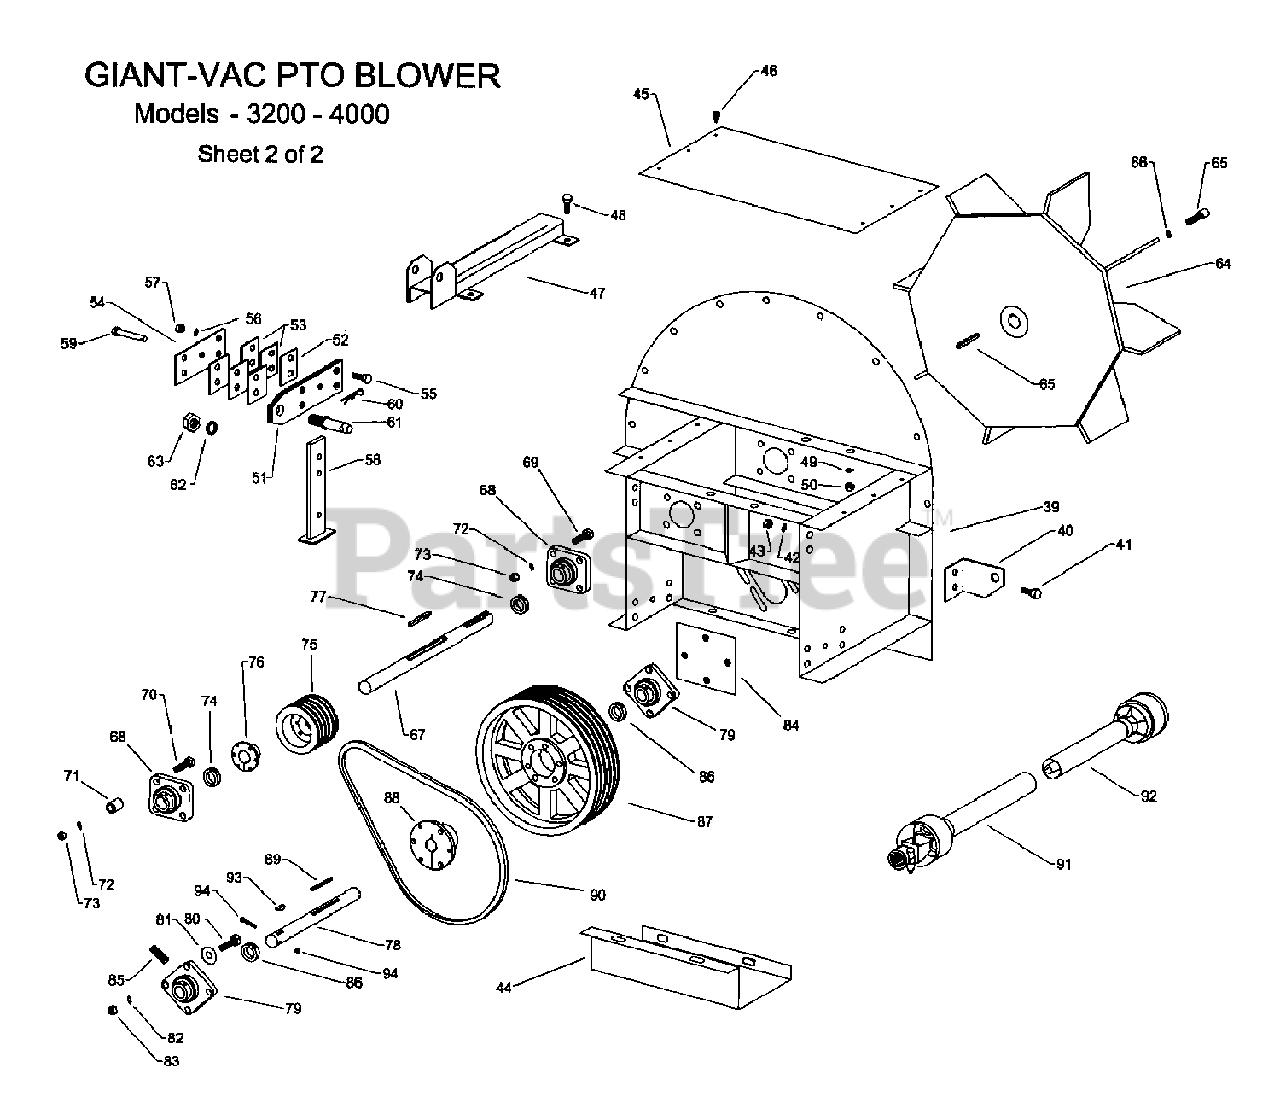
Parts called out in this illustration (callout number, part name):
39	Blower back & shaft frame
40	Control rod guide bracket
41	1/2 x 1-1/4 hex bolt
42	1/2 lockwasher
43	1/2 hex nut
44	Shaft frame bottom cover
45	Shaft frame top cover plate
46	#12 x 3/4 self tapping screw
47	Top hitch point bracket
48	1/2 x 1-1/4 hex bolt
49	1/2 lockwasher
50	1/2 hex nut
51	Hitch lower point plate
52	Jack stand spacer - 1/8
53	Jack stand spacer - 1/4
54	Jack stand side support plate
55	1/2 x 3-1/2 hex bolt
56	1/2 lockwasher
57	1/2 hex nut
58	Jack stand
59	Jack stand pin
60	Jack stand hair clip
61	Hitch pin
62	7/8 hitch pin lockwasher
63	7/8 hitch pin nut
64	Impeller, 33"
64	Impeller, 34"
65	Impeller bolt & key (5/8 x 3)
66	5/8 lockwasher
67	Impeller shaft
68	Impeller shaft bearing
69	1/2 x 1-3/4 hex bolt (impeller shaft inner bearing)
70	1/2 x 2-1/2 hex bolt (impeller shaft outer bearing)
71	Impeller shaft outer bearing spacer
72	1/2 lockwasher
73	1/2 hex nut
74	Impeller shaft collar
75	Impeller shaft pulley (4V)
75	Impeller shaft pulley (5V)
76	Impeller shaft pulley hub assembly (w/hardware)
77	Key - 3/8 x 3-1/2
78	Lower input shaft
79	Lower input shaft bearing
80	1/2 x 1-3/4 hex bolt
81	1/2 flatwasher
82	1/2 lockwasher
83	1/2 hex nut
84	Lower input shaft inner bearing bolt plate
85	1/2 x 4 Allen head pusher bolt
86	Lower input shaft locking collar
87	Lower input shaft pulley (4V)
87	Lower input shaft pulley (5V)
88	Lower input shaft pulley hub ass’y (w/hardware)
89	Key - 1/4 x 2-1/4
90	Drive belts (4 to a set)
90	Drive belts (5 to a set)
91	Drive shaft - tractor end*
92	Drive shaft - unit end*
93	5/16 drive shaft key
94	¼ x 2-1/2 bolt & nut
